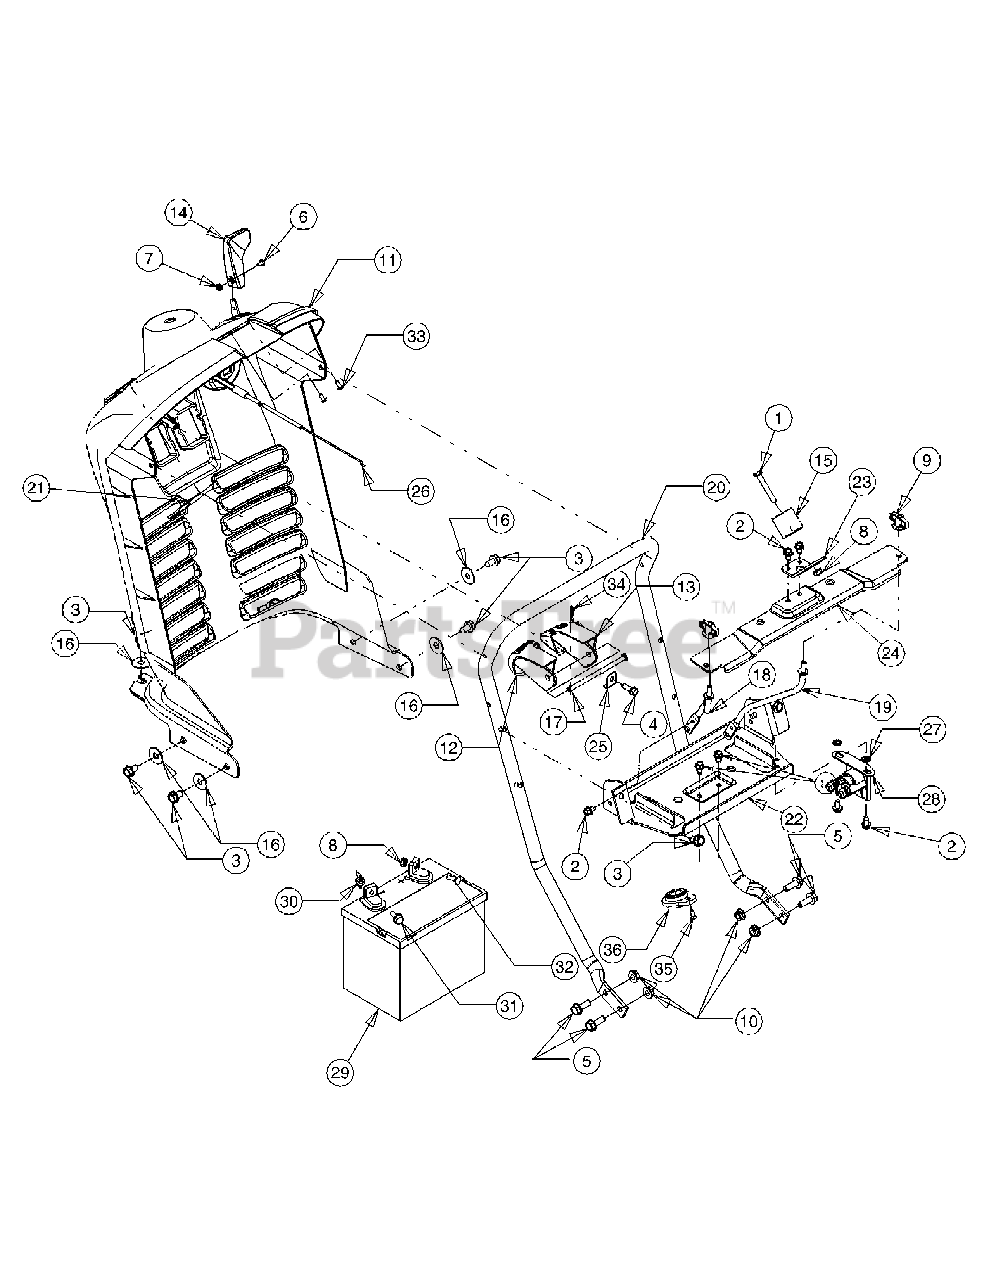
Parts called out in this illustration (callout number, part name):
1	Screw, 1/4-20, 1.75, Gr5
2	Screw, Self-tapping, 1/4-20, 0.500
3	Screw, 5/16-18, 0.625
4	Screw, 1/4-15, 0.750
5	Screw, 5/16-18, .875, Gr5
6	Screw, Machine, #8-32, 0.375, Trus Phillips
7	Nut, 8-32
8	Nut, Hex, 1/4-20, Sems
9	Nut, Wing, 1/4-20 w/ Bell Washer
10	Nut, Flange Lock, 5/16-18, Gr5
12	Lever, Dash, Cruise
13	Lever, Dash, Brake
14	Knob, Throttle Control
15	Roller, Latch, Hood
16	Washer, Flat, .349 x 1.00 x .063
17	Rod, .250 Dia x 4.25 Lg.
18	Rod, Support, Side Panel RH
19	Rod, Support, Side Panel LH
26	Control, Choke, 23 Lg.
27	Washer, External Lock, 1/4
28	Solenoid, 12V, 100 Amp
29	Battery, 270 CCA, Wet
30	Nut, Wing, 1/4-20
31	Screw, Shoulder, 1/4-20, .25 x .15
32	Screw, 1/4-20, .620, Gr5
33	Screw, #10-24 X .375
34	Internal Cotter Pin, .072 x 1.13
35	Screw, Oval Countersunk, #10-16 X .625
36	Bearing, Steering Column, .634 ID x 1.36
